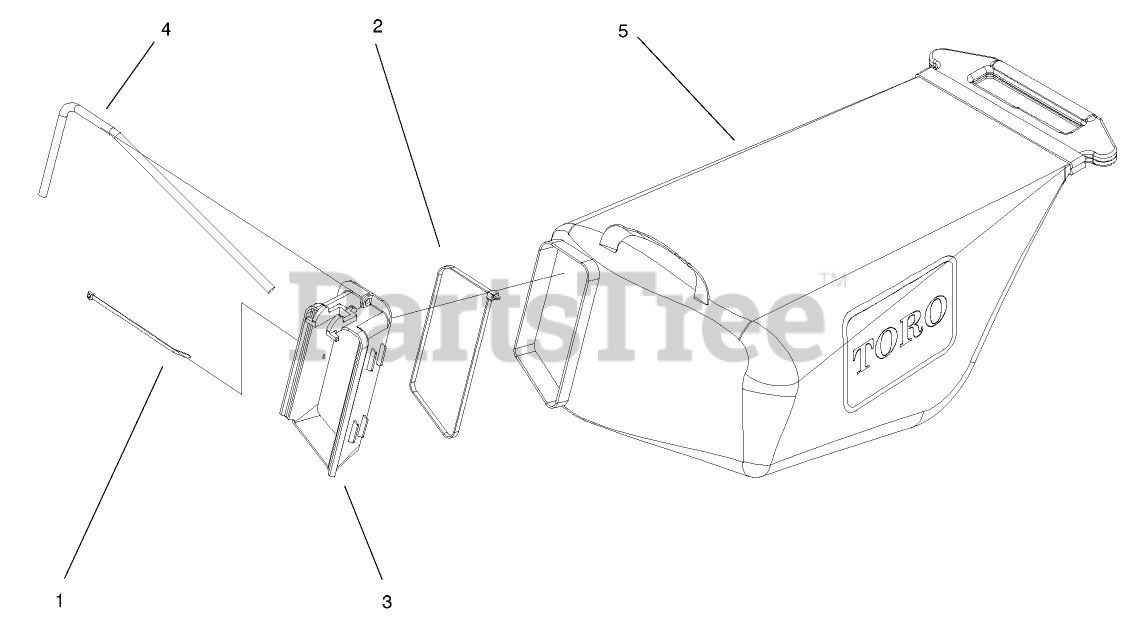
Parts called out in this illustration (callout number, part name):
1	TIE-CABLE
2	STRAP-TIE
3	Chute-Bag,Inlet
4	WIRE-SUPPORT,BAG
5	Bag-Grass,Ts
